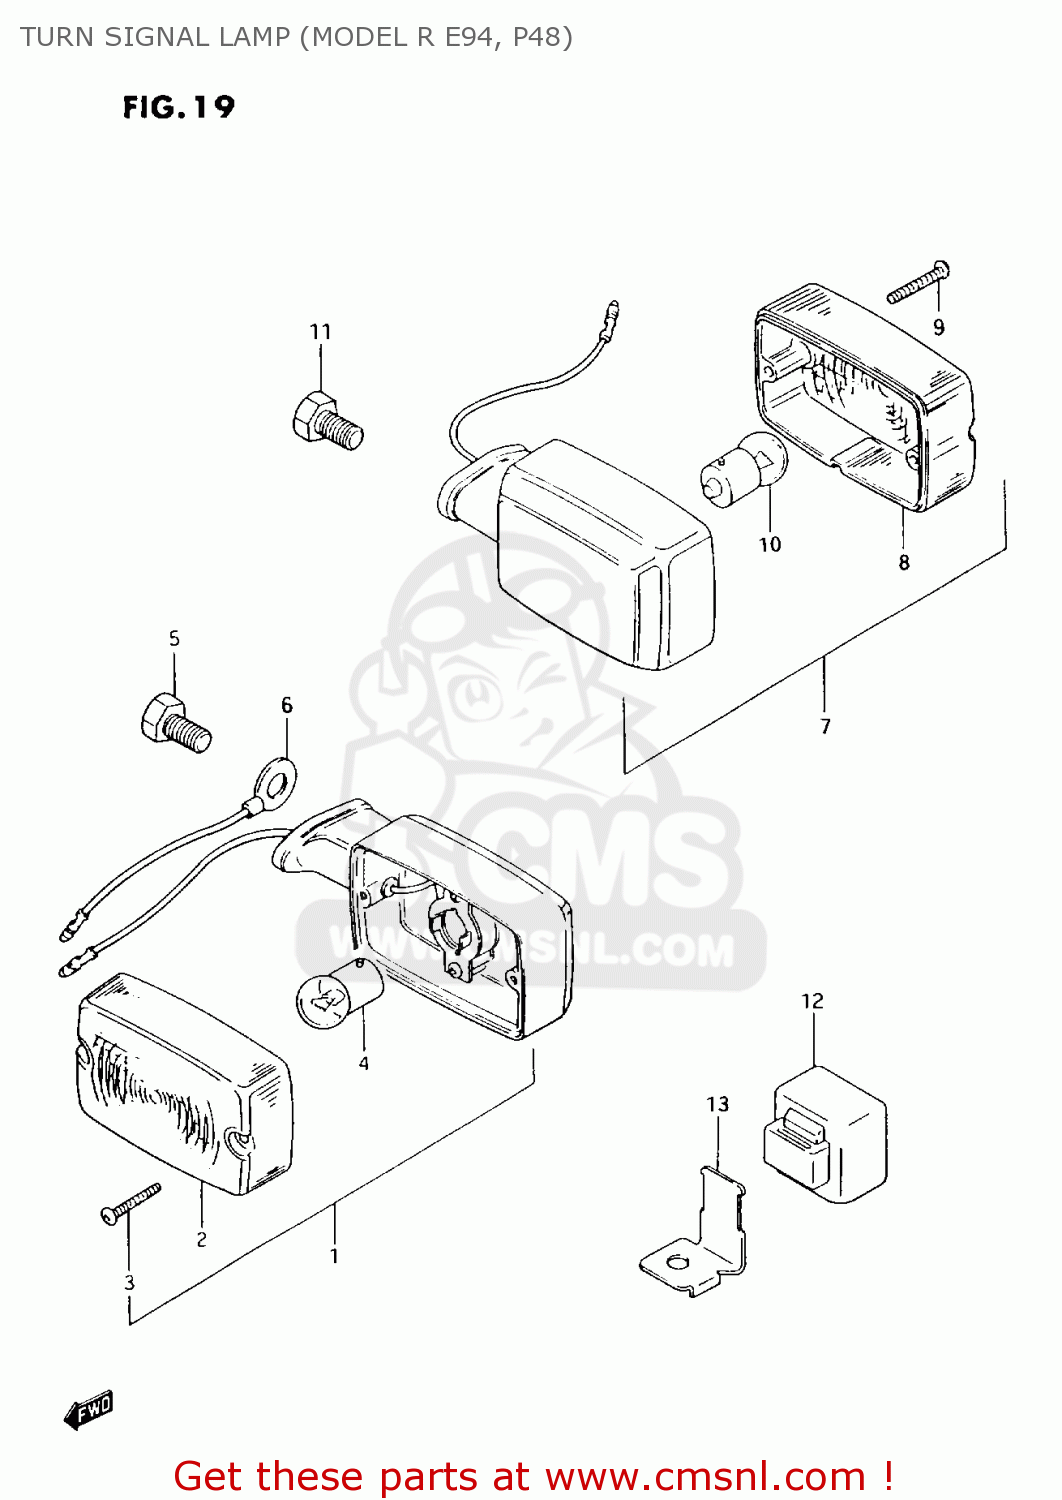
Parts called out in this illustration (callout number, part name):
1	LAMP ASSY, REAR TURN SIGNAL
2	LENS
3	SCREW
4	BULB(6V8W,STANLEY,A4115)
5	BOLT, UPPER
6	LEAD WIRE,EARTH
7	LAMP ASSY, REAR TURN SIGNAL
8	LENS
9	SCREW
10	BULB(6V8W,STANLEY,A4115)
11	BOLT, UPPER
12	RELAY,TURN SIGNAL
13	BRACKET,TURN SIGNAL RELAY
